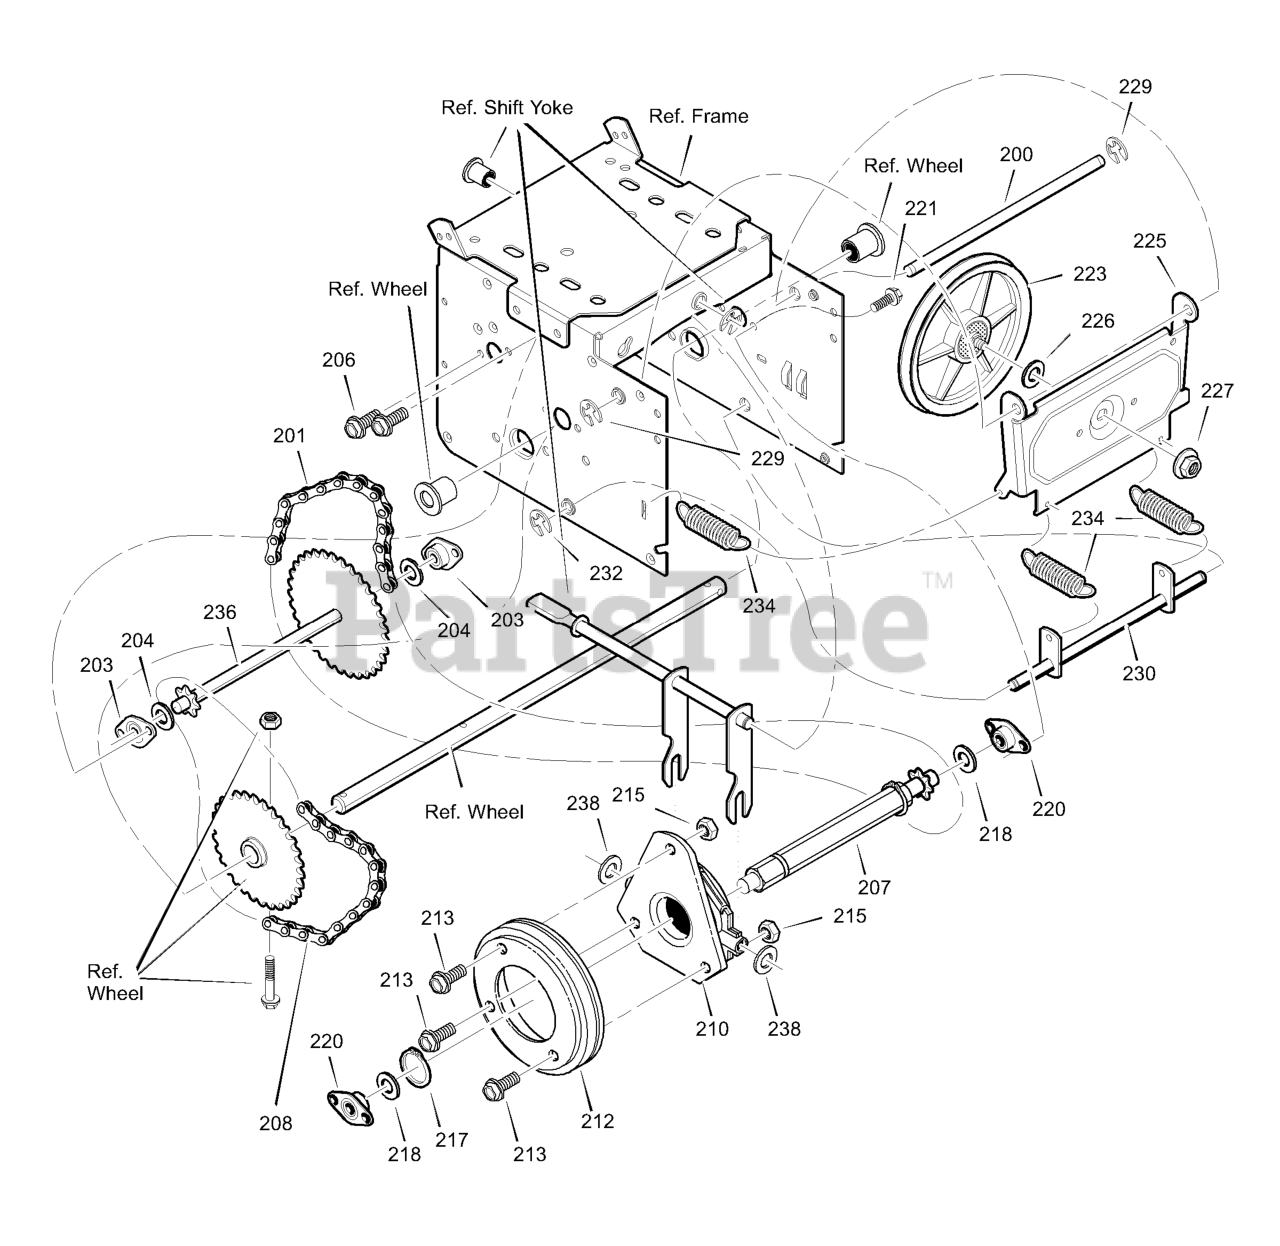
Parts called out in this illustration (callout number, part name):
200	LF AXLE, SWING PLATE YZ
201	CHAIN, ROLLER 420 x 19.00 LG
203	BEARING AND RETAINER, ASSY
206	SCREW, TAP 5/16-18 x 0.5
207	ASSY, HEX SHAFT
208	CHAIN, ROLLER 420 x 18.00 LG
210	BEARING, TRUNION CLUTCH R
212	WHEEL, FRICTION DISC
213	SCREW, 1/4-20 x 0.63
215	NUT, KEPS HEX 1/4-20
217	RING, RETEXT
220	BEARING AND RETAINER, ASSY
221	SCREW, TAP 5/16-18 X .50
223	ASSY., FRICTION PULLEY
225	LF PLATE, SWINGING YZ
226	SPACER, FRICTION PULLEY
227	NUT, FLANGE LOCK 3/8-24
229	RETAINER, RING
230	LF ASSY, SPRING LINK YZ
232	RETAINER, RING
234	SPRING, EXTENSION
236	WLD, INTERMED SPROCKET 33T/7
238	WASHER, FLAT
